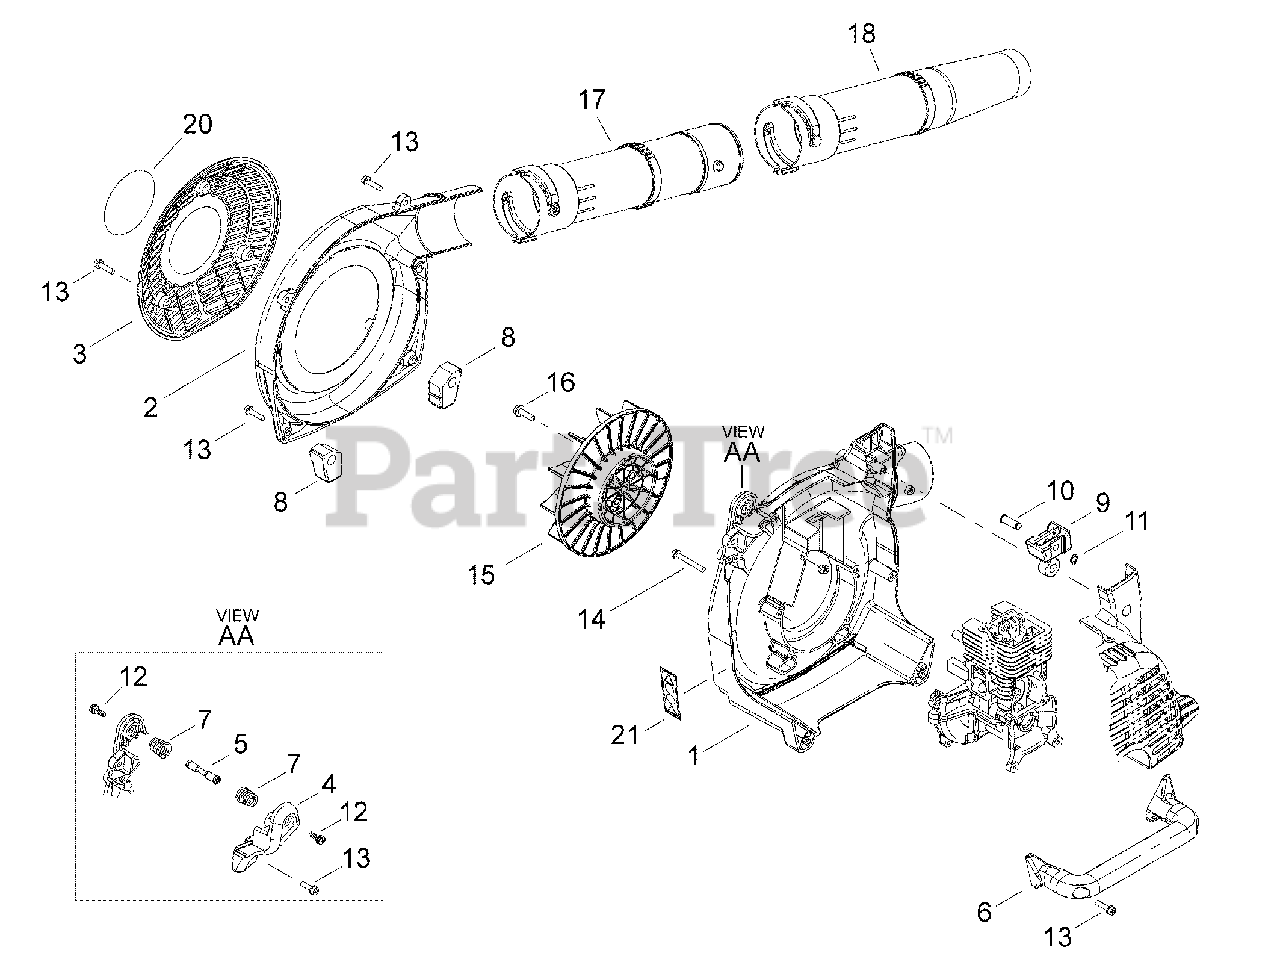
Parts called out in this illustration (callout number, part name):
1	CASE, FAN
2	COVER, FAN
3	COVER, INTAKE
4	MOUNT, HANDLE
5	NUT, HANDLE 5
6	HANDLE, SIDE
7	SPRING, COIL Ø18ר14
8	CUSHION
9	CUSHION, AV
10	PIN, LOCK
11	RING, SNAP 8 MM
12	SCREW, ADHESIVE M5×16
13	BOLT M5×20
14	BOLT M5×40
15	FAN
16	BOLT M6×20
17	TUBE, BLOWER
18	TUBE, BLOWER - ROUND NOZZLE
20	LABEL, E4 A3000
21	LABEL, CAUTION
